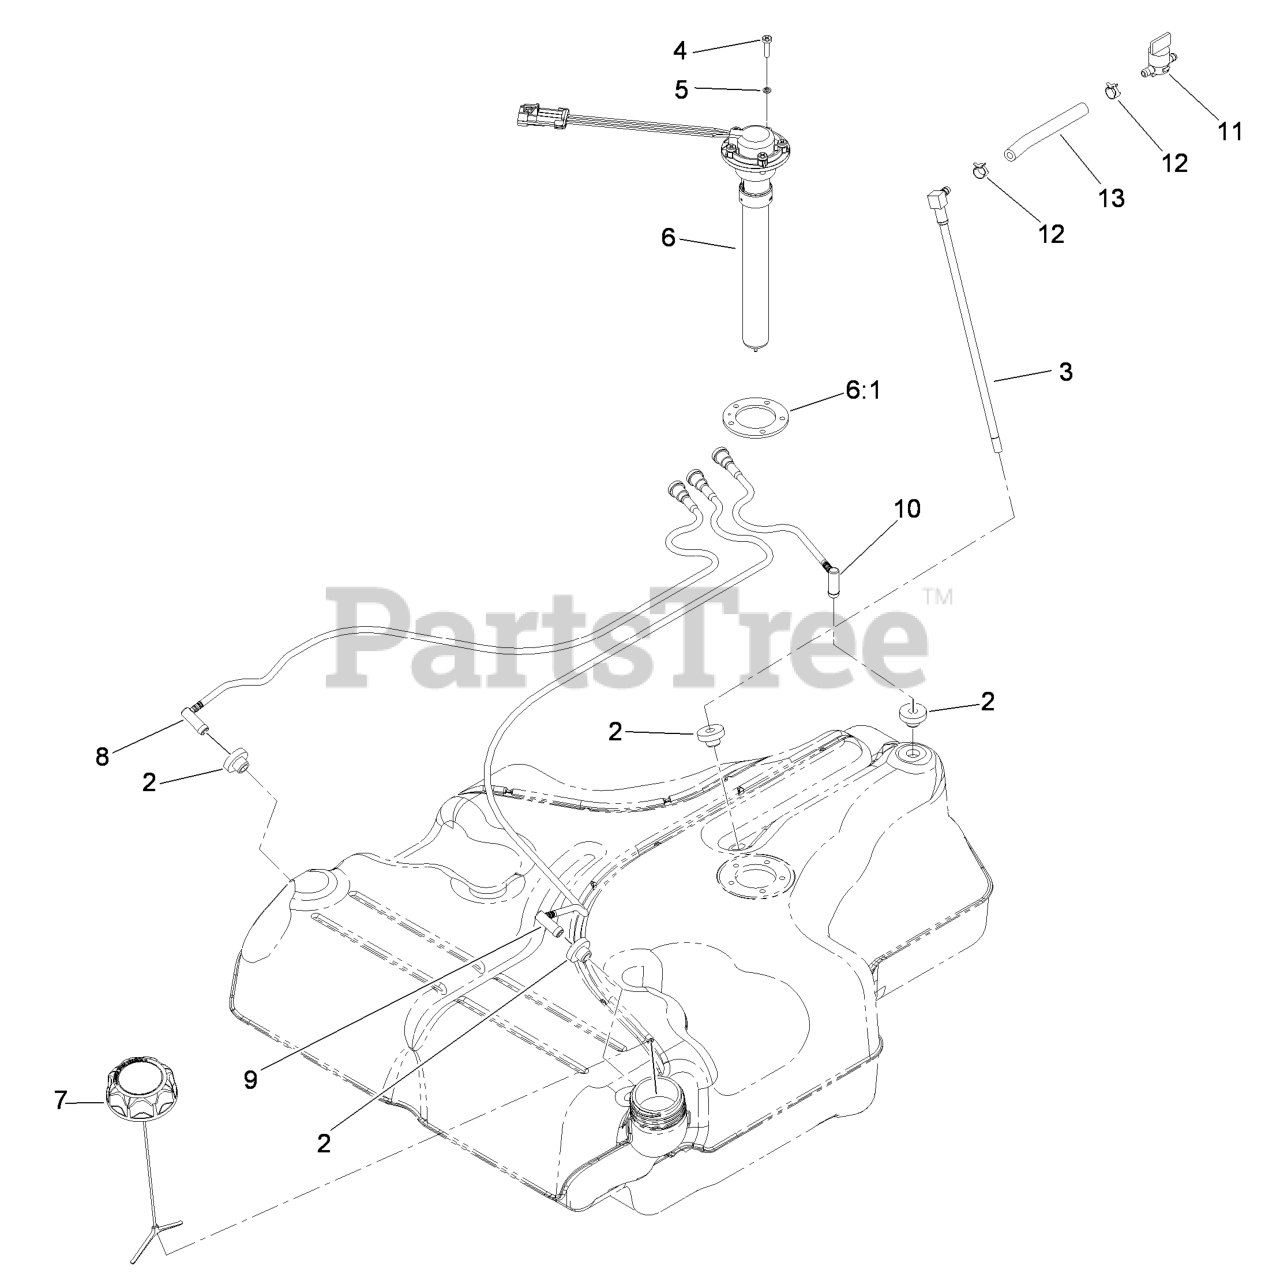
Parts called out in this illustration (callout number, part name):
2	BUSHING
3	FUEL LINE KIT (WITH GROMMET)
4	SCREW-PAN
5	WASHER-LOCK
6:1	GASKET-SENDER, FUEL
8	RH VENT LINE KIT (WITH GROMMET)
9	LH VENT LINE KIT (WITH GROMMET)
10	REAR VENT LINE KIT (WITH GROMMET)
11	VALVE-FUEL
12	CLAMP-HOSE
13	HOSE-FUEL
